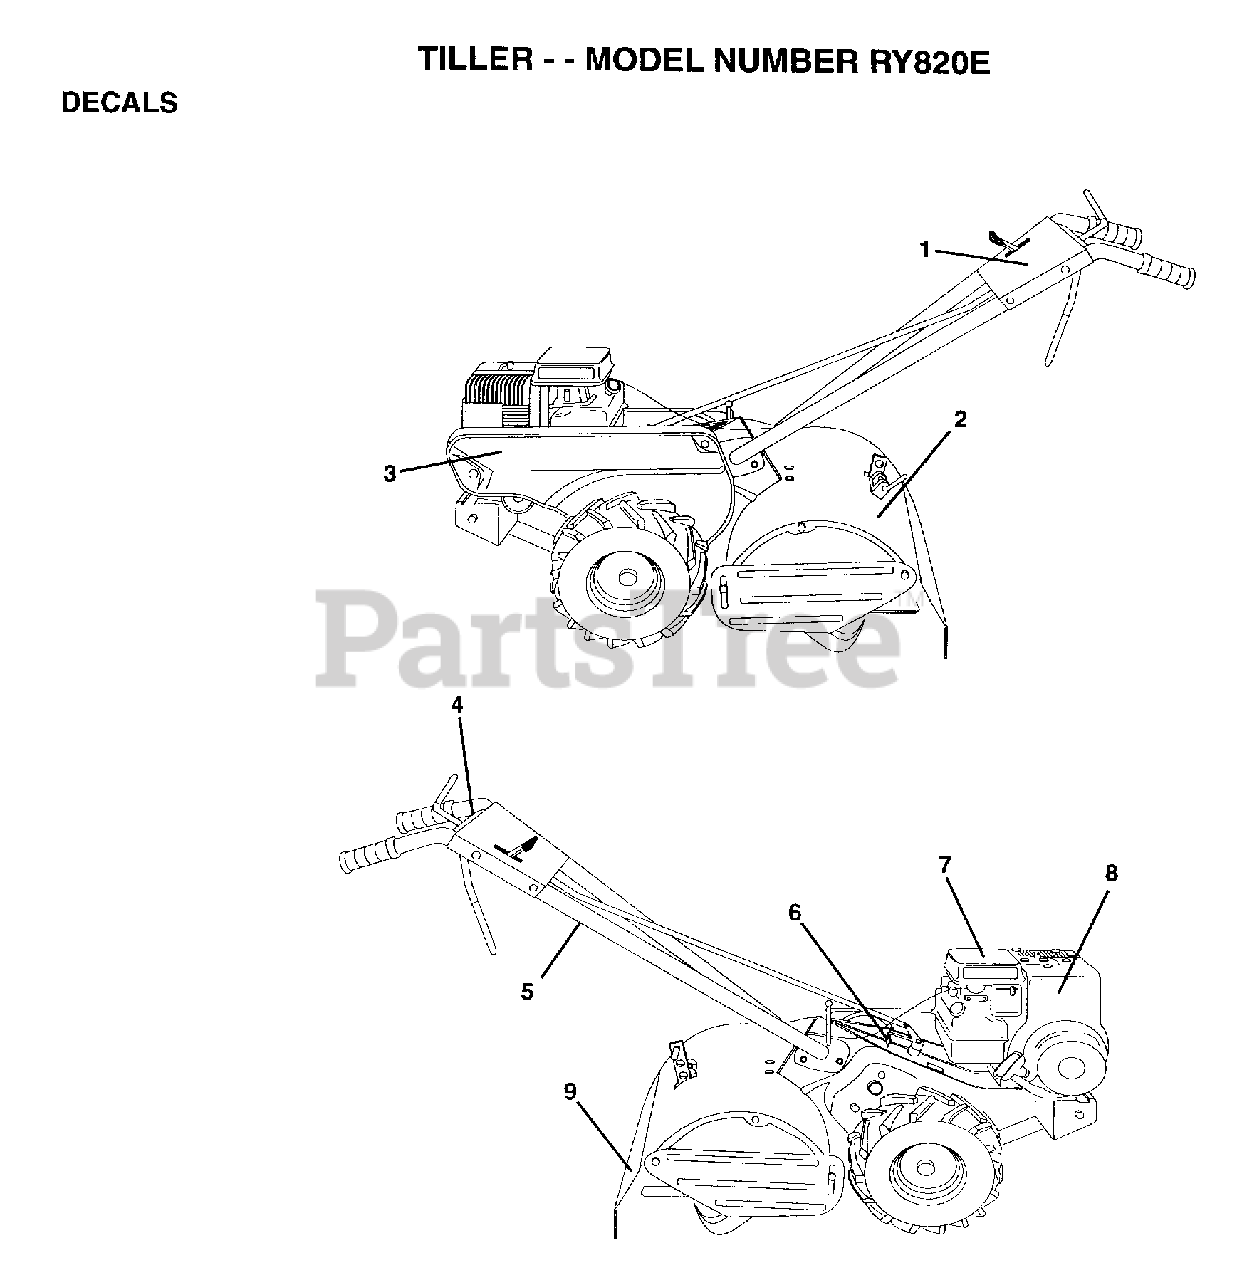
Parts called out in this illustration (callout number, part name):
3	DECAL, LOGO
5	DECAL TI
7	DECAL TI
8	DECAL, BRIGGS & STRATTON
